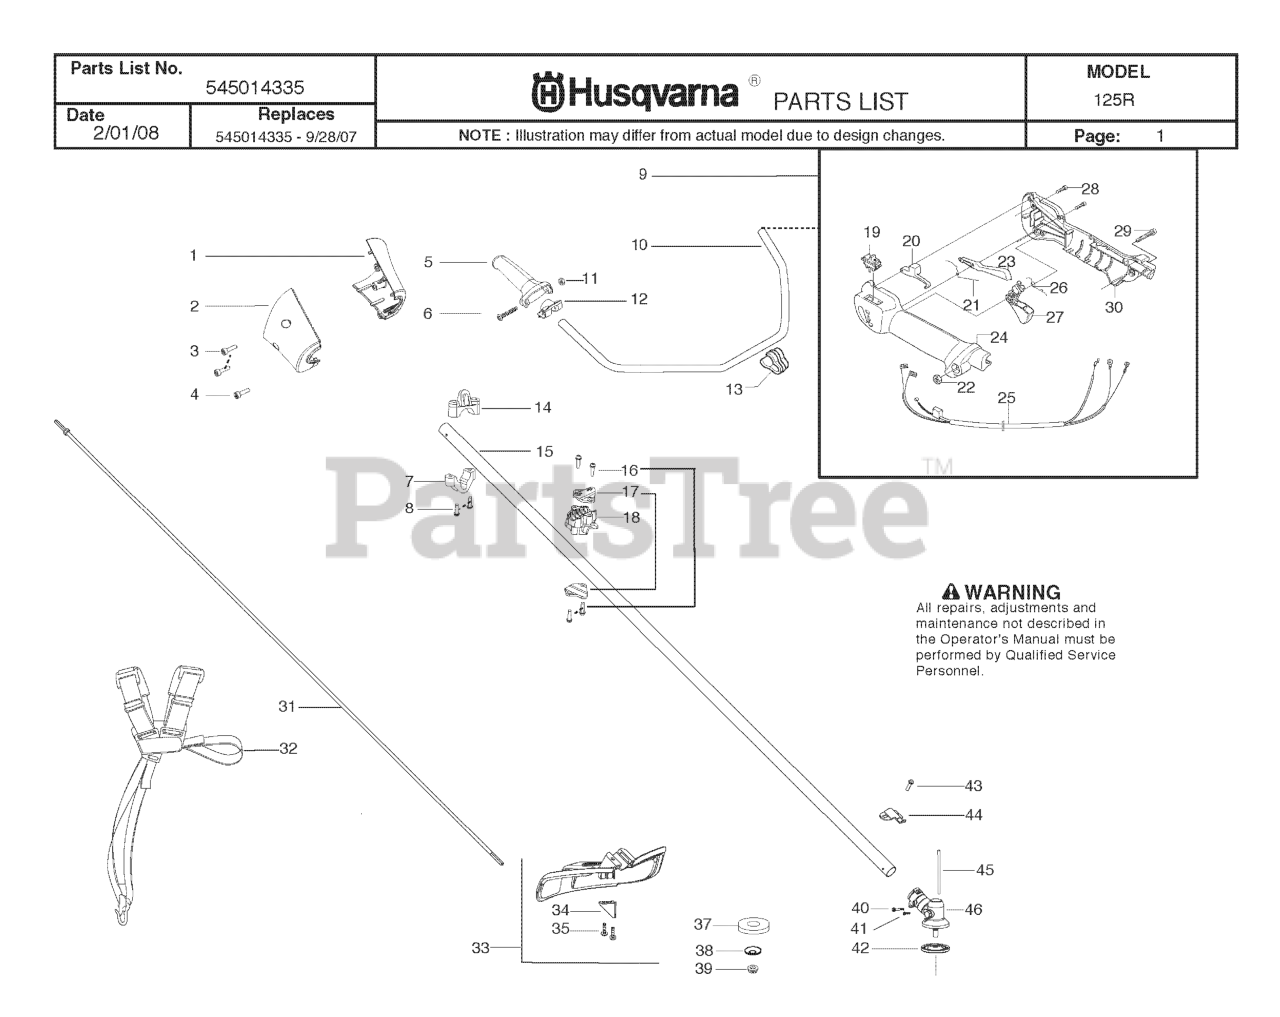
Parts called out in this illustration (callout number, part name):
1	NOSE CONE BH LEFT
2	NOSE CONE BH RIGHT
4	SCREW M4 X 1.75 PT 16MM
7	CLAMP HARNESS LOWER
9	ASSY THROTTLE HOUSING
14	CLAMP HARNESS UPPER
15	KIT-DRIVESHAFT(INCL. 40.41.44.
17	CLAMP BRACKET
19	STOP BUTTON
20	LOCKOUT STARTER THROTTLE
23	THROTTLE LOCK
25	ASSY CABLE WIRE HARNESS
27	THROTTLE TRIGGER
29	SCREW
32	Harness w/warning
33	KIT COBI SHIELD
34	Limiter - Line
37	SUPPORTING CUP
38	SUPPORT FLANGE
39	GEARHEAD NUT - BRUSHCUTTER
40	SCREW - CARB. ADAPTOR
42	DRIVE DISC
43	SCREW 1/4-20 X 7/8 (TAP
44	BRACKET SHIELD STRAIGHT SHAFT
45	LOCKING PIN
46	ASSY GEARBOX
